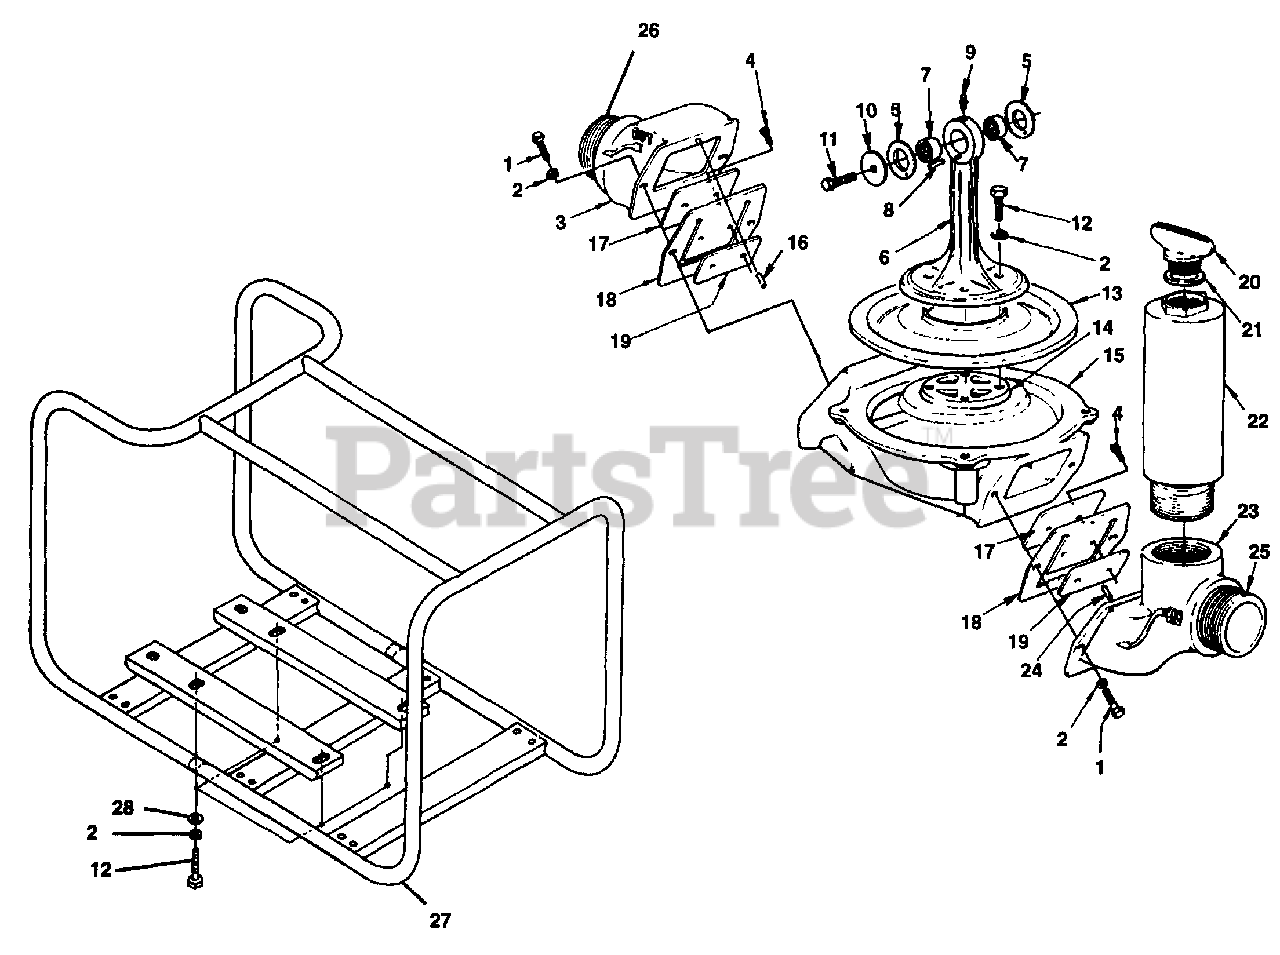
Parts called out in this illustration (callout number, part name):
1	SCREW, Hex hd. (1/2-13 X 1 3/4)
2	WASHER, Lock (1/2")
3	FITTING-Discharge
4	SCREW, fil hd., 10-32 x 1/2 4
5	WASHER, thrust
6	PUMP ROD
7	BEARING, needle
8	PIN-Coiled spring
9	GREASE FITTING
11	SCREW, hex hd., 3/8-16 x 3/4
12	SCREW, hex hd., 1/2-13 x 1 1/4
13	DIAPHRAGM
14	PLATE, diaphragm
15	PUMP BODY
16	PIN-Roll
17	VALVE, plate
18	VALVE, flapper
19	WEIGHT, valve
20	PLUG-Wing
21	PLUG GASKET
22	STANDPIPE - 3"
23	SUCTION FITTING
24	PIN, roll
25	NIPPLE - 3"
26	NIPPLE - 3"
27	ROLL CAGE
28	WASHER FLAT 1/2"
